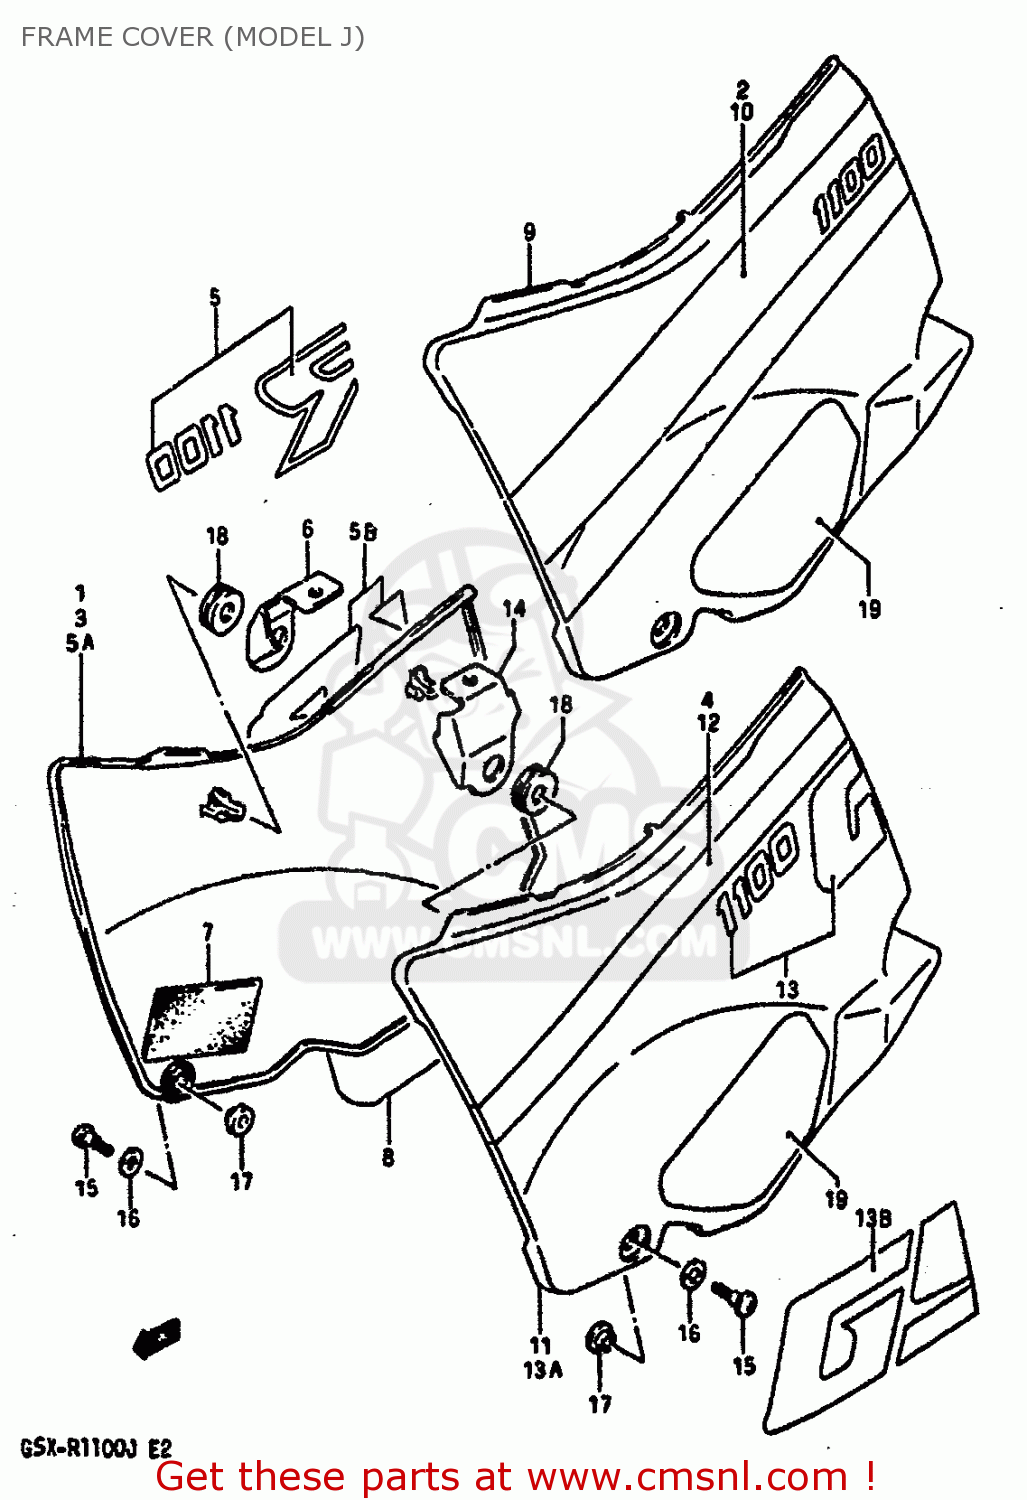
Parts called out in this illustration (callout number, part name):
1	COVER,FRAME,RIGHT
2	TAPE,FRAME COVER,RIGHT
3	COVER,FRAME,RIGHT
4	TAPE,FRAME COVER,RIGHT
5	EMBLEM,RIGHT
5A	COVER FRAME RH
5B	EMBLEM,RH (GOLD)
6	HOLDER,FRAME COVER,RIGHT
7	RUBBER,FRAME COVER,RIGHT
8	PROTECTOR,FRAME COVER
9	COVER,FRAME,LEFT
10	TAPE,FRAME COVER,LEFT
11	COVER,FRAME,LEFT
12	TAPE,FRAME COVER,LEFT
13	EMBLEM,LEFT
13A	COVER FRAME LH
13B	EMBLEM,FRAME COVER,L(GOLD)
14	HOLDER, FRAME COVER LH
15	EMBLEM
16	CUSHION
17	WASHER
18	CUSHION
19	WASHER
20	CUSHION
21	PROTECTOR,FRAME COVER LH
